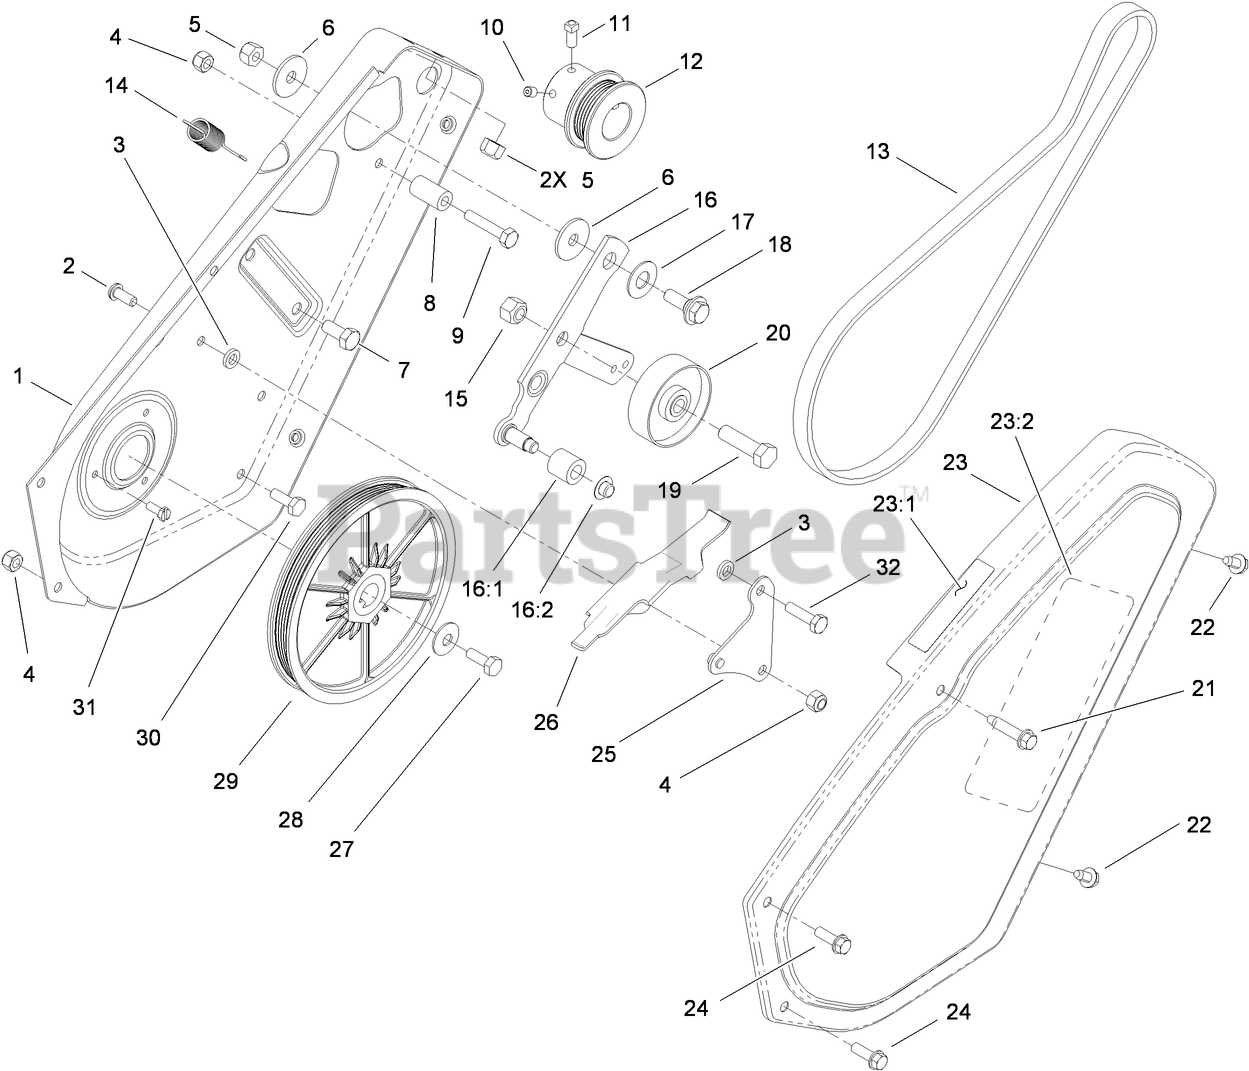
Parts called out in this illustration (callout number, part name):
1	PLATE-SIDE, LH
2	SCREW-HSBH
3	SPACER-PLATE, PIVOT
4	NUT-LOCK, NI
5	NUT-LOCK, NI
6	WASHER-PIVOT
7	SCREW-HH
8	SLEEVE-GUIDE, BELT
9	SCREW-HH
10	SCREW-HSH
11	SCREW-SQH
12	PULLEY-ENGINE
13	BELT-DRIVE
14	SPRING-EXTENSION
15	NUT-LOCK, CONE
16	IDLER ARM ASM
16:1	ROLLER-BRAKE
16:2	NUT-PUSH
17	WASHER
18	SCREW-SHOULDER
19	SCREW-HH
20	PULLEY-IDLER
21	SCREW-HWH
22	SCREW
23	COVER-DRIVE
23:1	DECAL-WARNING
23:2	DECAL
24	SCREW-HWH
25	PIVOT PLATE ASM
26	BRAKE-ARM
27	SCREW-HH
28	WASHER-BELLEVILLE
29	PULLEY ROTOR ASM
30	SCREW-HH
31	SCREW-SHH
32	SCREW-HH
